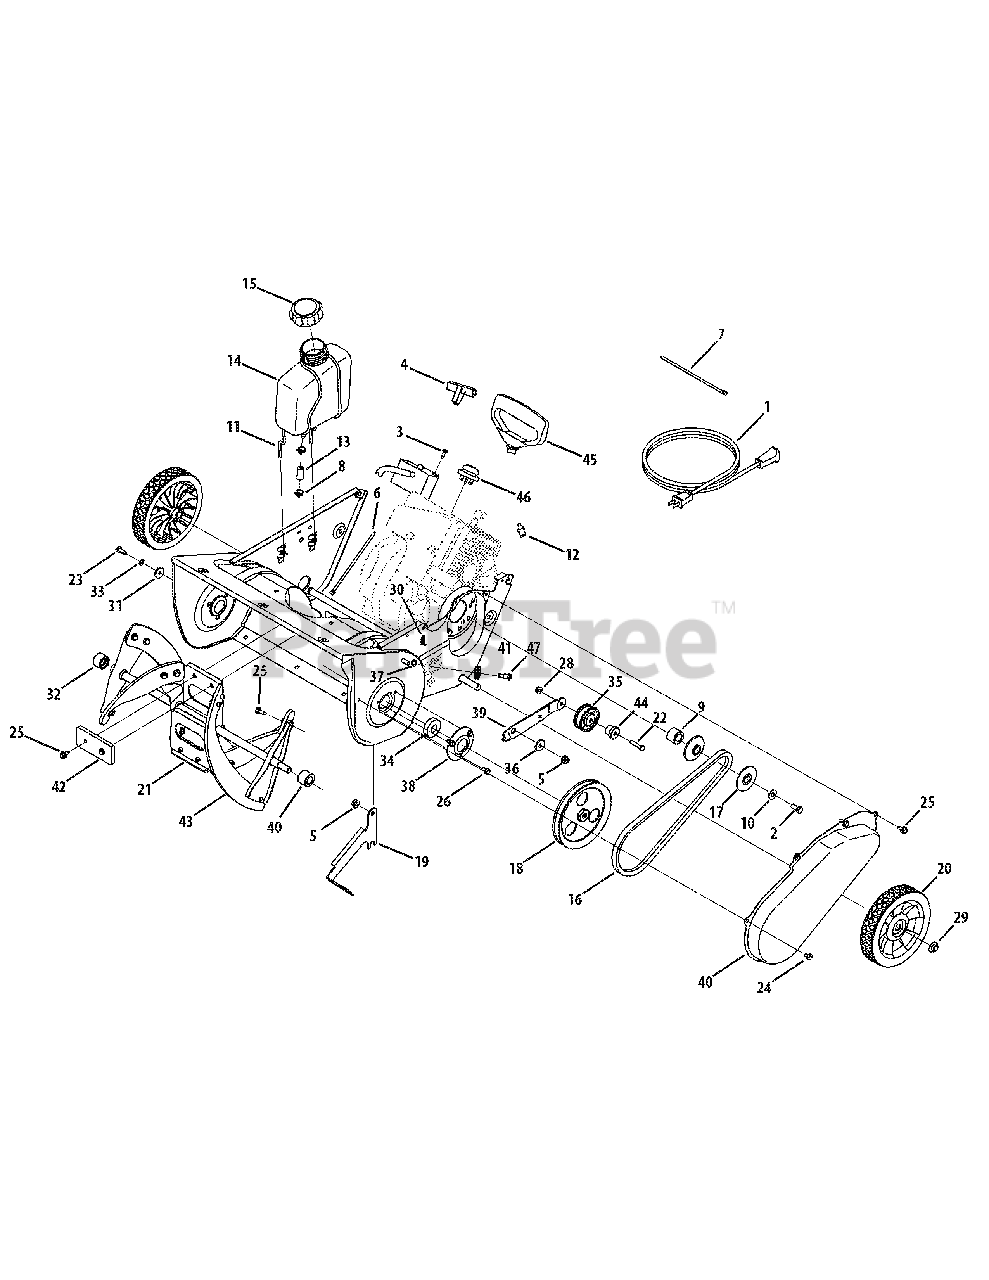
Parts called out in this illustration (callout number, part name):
1	Extension Cord
2	Hex Screw, 5/16-24 x .75
3	Screw, #10-16 x .625
4	Recoil Handle
5	Hex Flange Lock Nut, 5/16-18
6	Cable Tie
7	Push Mount Cable Tie
8	Clamp, Hose
9	Spcr., .630 x .880 x .747
10	Bell Wash., .340 x .872 x .060
11	Gas Tank Support Wire
12	Choke Lever Knob
13	Hose, Fuel Line
14	Tank, Fuel
15	Cap, Fuel
16	V-Belt 3/8 X 34.4
16	V-Belt 1/2 X 35
17	Pulley Half, .625 ID x 2.25 OD
18	Pulley, V Type, 3/8 x 6.0 OD
18	Pulley, V Type, 1/2 x 6.0 OD
20	Wheel, 7 x 1.5 Star Dia. Tread
22	Hex Screw, 1/4-20 x 1.00 Gr. 5
23	Hex Screw 1/4-20 x .75 Gr. 5
24	Self-tapp Screw, 1/4-20 x .375
25	Hex Screw, 1/4-14 x 0.625"
26	Screw, 1/4-14 x .500
28	Hex Flange Lock Nut, 1/4-20
29	Push Cap, 1/2"
30	Extension Spring
31	Flat Washer .265 x .938 x .120
32	Spacer, Auger, RH
33	Lock Washer, 1/4
34	Ball Bearing
35	Idler Pulley
36	Shoulder Spacer .25
37	Hex Lock Nut 1/4-28
41	Cable Roller
42	Rubber Paddle
43	Crescent Spiral
44	Shldr., Spcr., .260 x .785 x .538
45	Recoil Handle, Mitten
46	Primer
47	Carriage Screw 1/4-28
48	Spacer, Auger, LH
